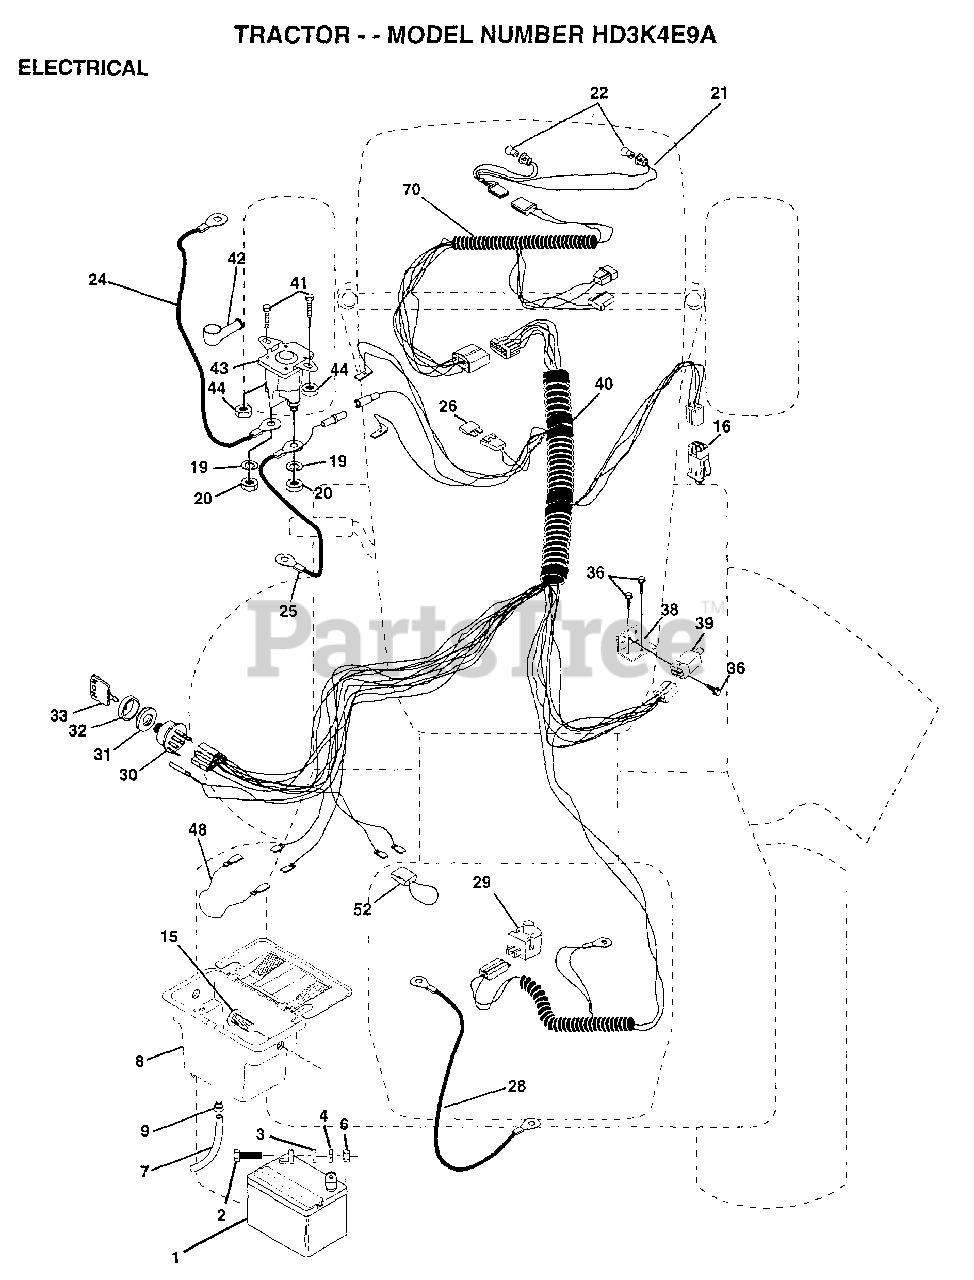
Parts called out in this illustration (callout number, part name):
2	BOLT LT
3	WASHER
4	LOCKWASHER
7	TUBE T
9	HOSE CLAMP T
15	FASTNER.SNAP-IN
16	SWITCH INTERLOCK
20	NUT
21	"HARNESS,LIGHT SOC"
22	HEADLAMP BULB
24	"CABLE T, BATTERY"
25	CABLE.BTRY.6GA.RD
26	FUSE HYT
28	CABLE T
29	SWITCH SEAT
30	SWITCH IGN 4POS
31	NUT IGNITION
32	COVER KEY SWITCH
33	KEY
36	SCREW
38	BRACKET SWITCH IN
39	SWITCH INTERLOCKT
40	HARNESS.IGNITION
41	BOLT HXHD FIN
44	NUT HXKEP 1/4X20
48	ADAPTER AMMETER
52	PROTECTION LOOP
70	HARNESS ENGINE
